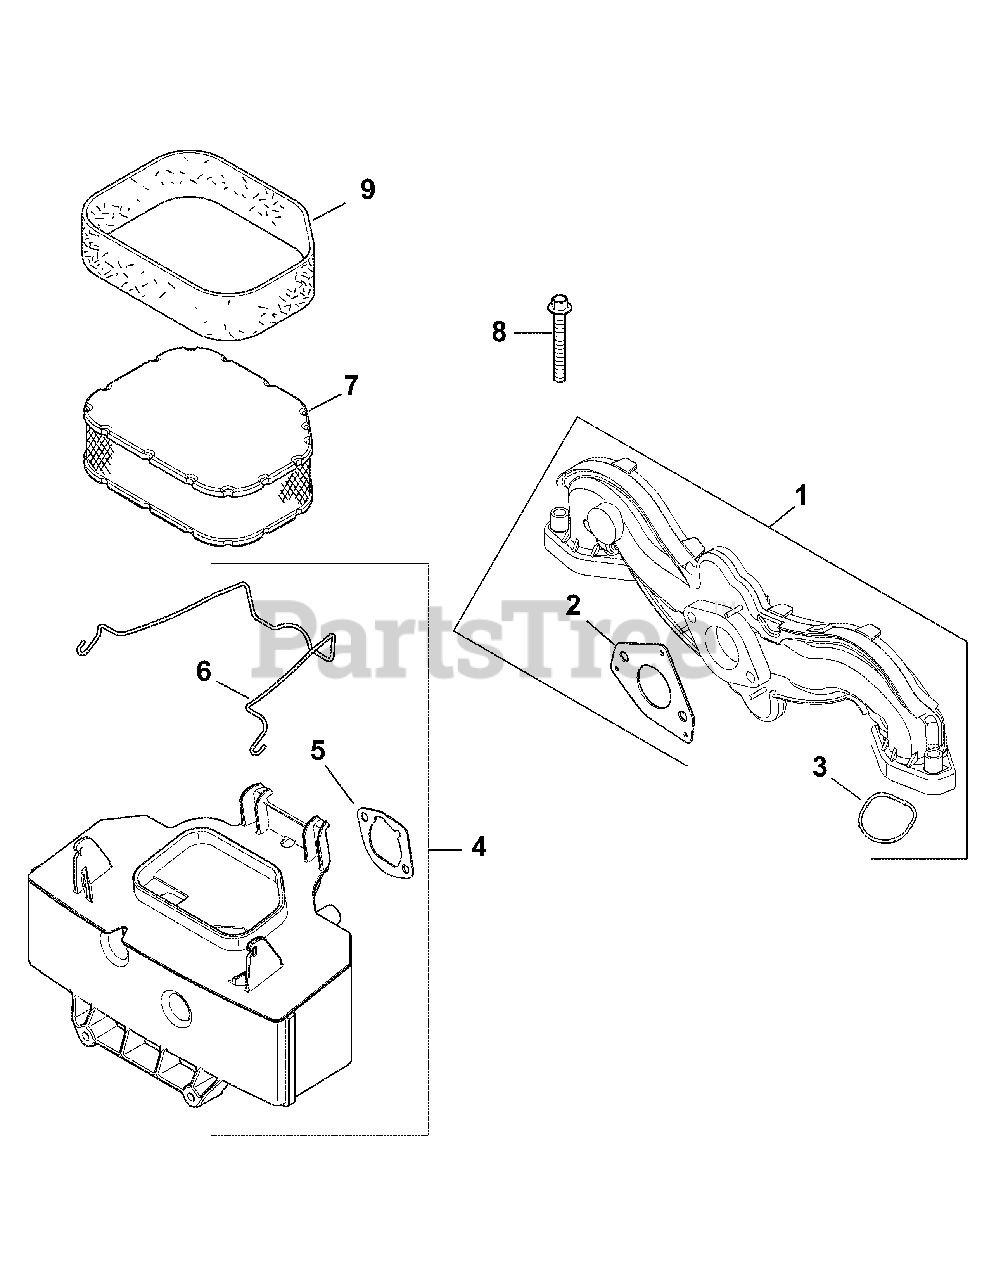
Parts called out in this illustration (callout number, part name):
1	Manifold, Intake (Includes 2, 3)
2	Gasket, Carburetor
3	O-Ring, Intake Port
4	Kit, Air Cleaner Base (Includes 5, 6)
5	Gasket, Air Cleaner Base
6	Latch, Air Cleaner Element
7	Element, Air Filter
8	Screw, FLG M6 x 1.0 x 40
9	Element, Pre-Cleaner
